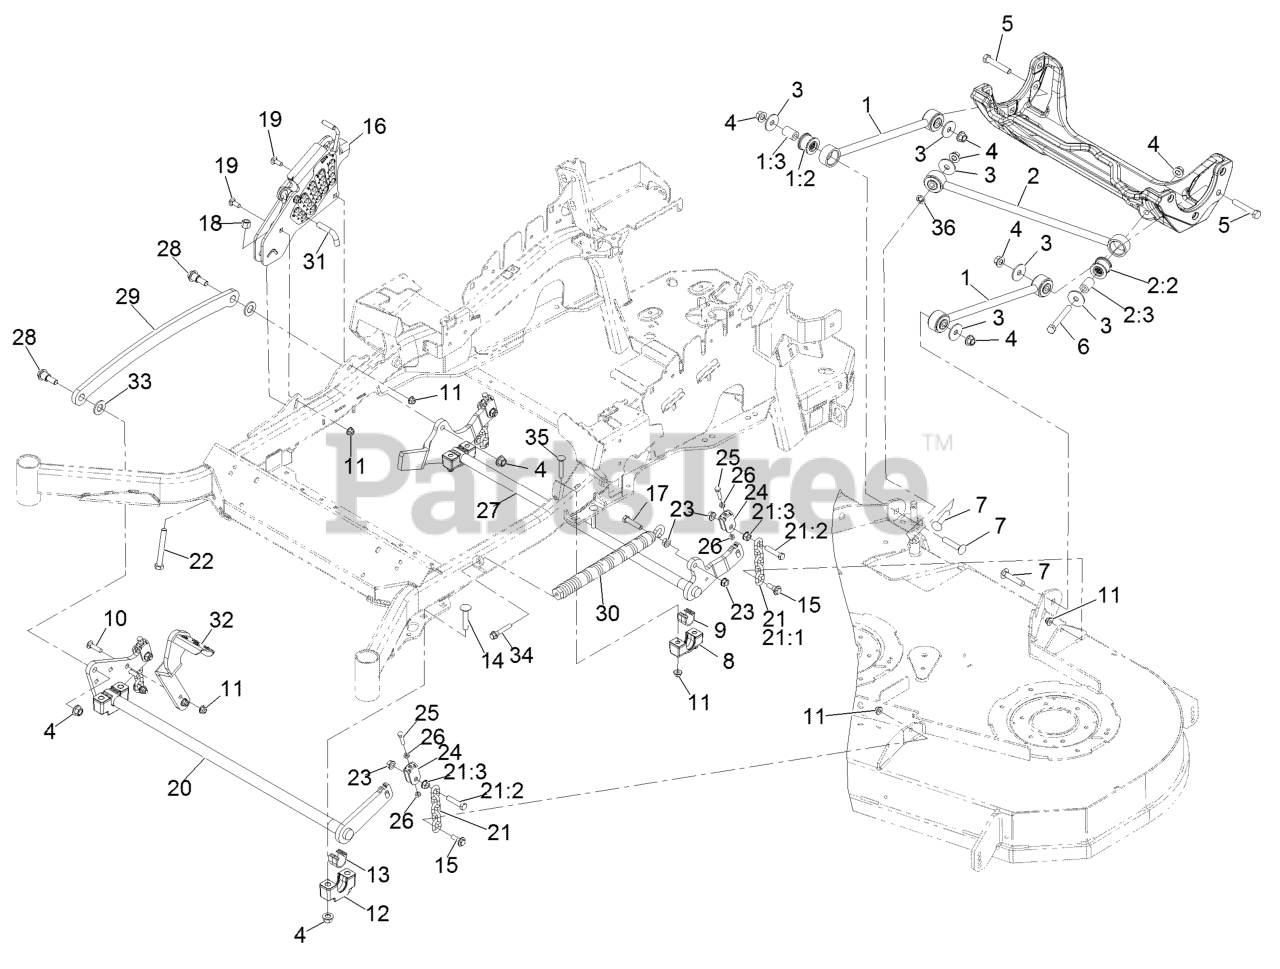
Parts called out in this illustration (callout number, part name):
1	Deck Strut ASM
1:2	Bushing-Suspension,Rubber
2	Panhard Rod ASM
2:2	Bushing-Suspension,Rubber
4	Nut-Lock 1/2-13
5	Screw-HH 1/2-13 X 3
6	Screw-HH 1/2-13 X 4
7	Bolt-Carriage 1/2-13 X 2 1/2
8	Support-Cross Shaft, Bearing Rear
9	Bearing-Cross Shaft, Rear
10	Bolt-Carriage 3/8-16 X 1 1/2
11	Nut-Nyloc 3/8-16 Flg
12	Support-Cross Shaft,Bearing
13	Bearing-Cross Shaft, Front
14	Bolt-Carriage 1/2-13 X 2 1/2 Spl Neck
15	Screw-Hex Flange 3/8-16 X .80
16	HOC ASM
17	Screw-HH 7/16-14 X 2
18	Nut-Nyloc 1/2-13
19	Bolt-Carriage 3/8-16 X 1
20	Decklift-Front
21	Deck Lift Chain ASM
21:1	Chain-Lift, Deck
21:2	Screw-HH 7/16-14 X 2
21:3	Nut-Whizlock 7/16-14
22	Bolt-HH 1/2-13 X 4 Tap
23	Nut-Whizlock 7/16-14
24	Yoke-Adjust, Deck
25	Screw-HH 5/16-18 X 1 1/4
26	Nut-Jam 5/16-18
27	Lift-Deck, Rear
28	Screw-Shoulder HHF 1/2-13 X 1.12
29	Link-Lift, Deck
30	Spring-Extension
31	Pin-HOC
32	Lever-Foot
33	Washer-3/4 Sae
34	Screw-Shcs 3/8-16 X 2.212
35	Bolt-Carriage 3/8-16 X 2 1/4
36	Nut-Push
